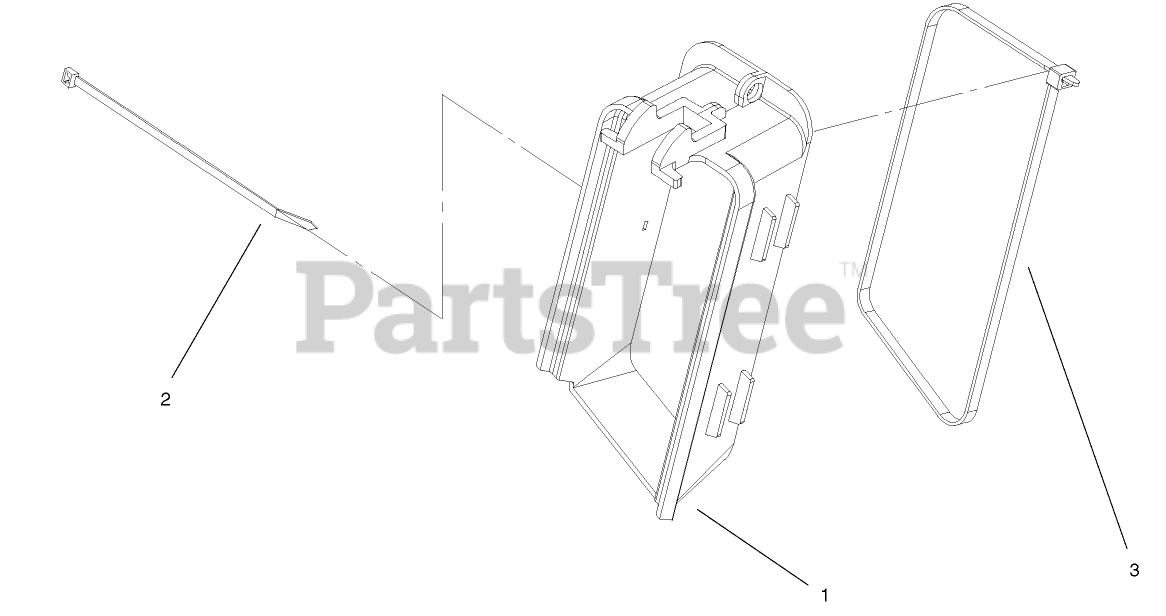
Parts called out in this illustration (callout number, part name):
1	Chute-Bag,Inlet
2	TIE-CABLE
3	STRAP-TIE
